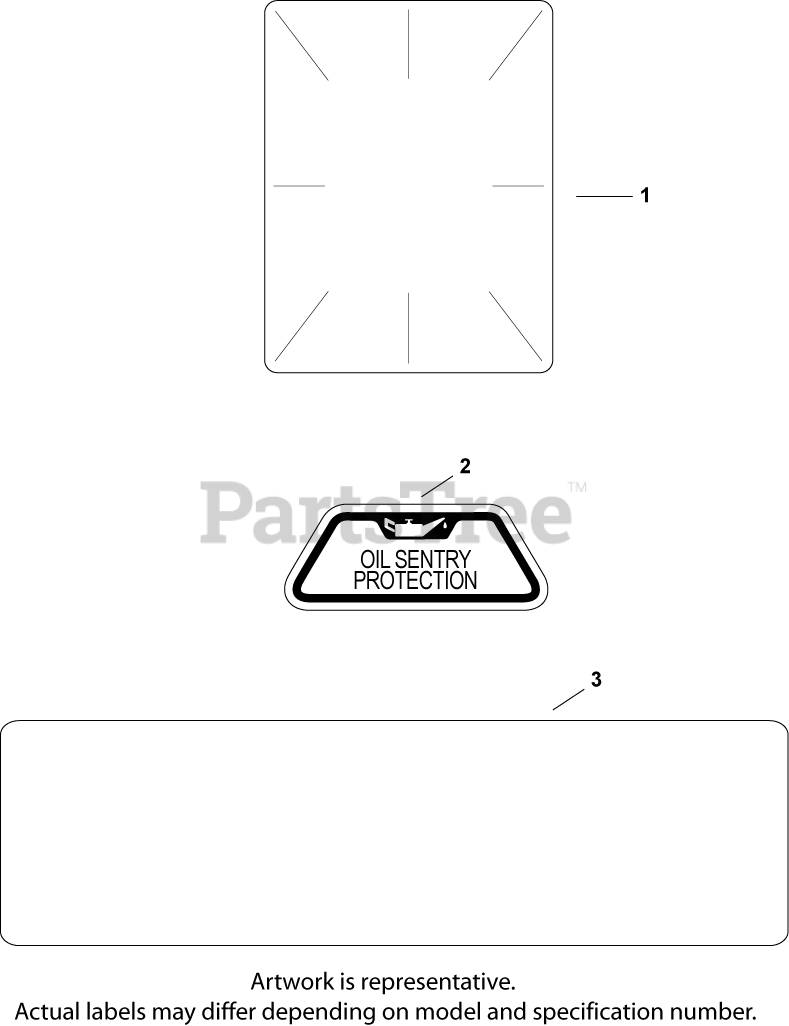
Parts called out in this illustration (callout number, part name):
1	DECAL, CLEAR LAMINATE USE 25 113 70-S
2	DECAL, OIL SENTRY - (#DSC)
3	DECAL, 23 HP - (#24113216S)
